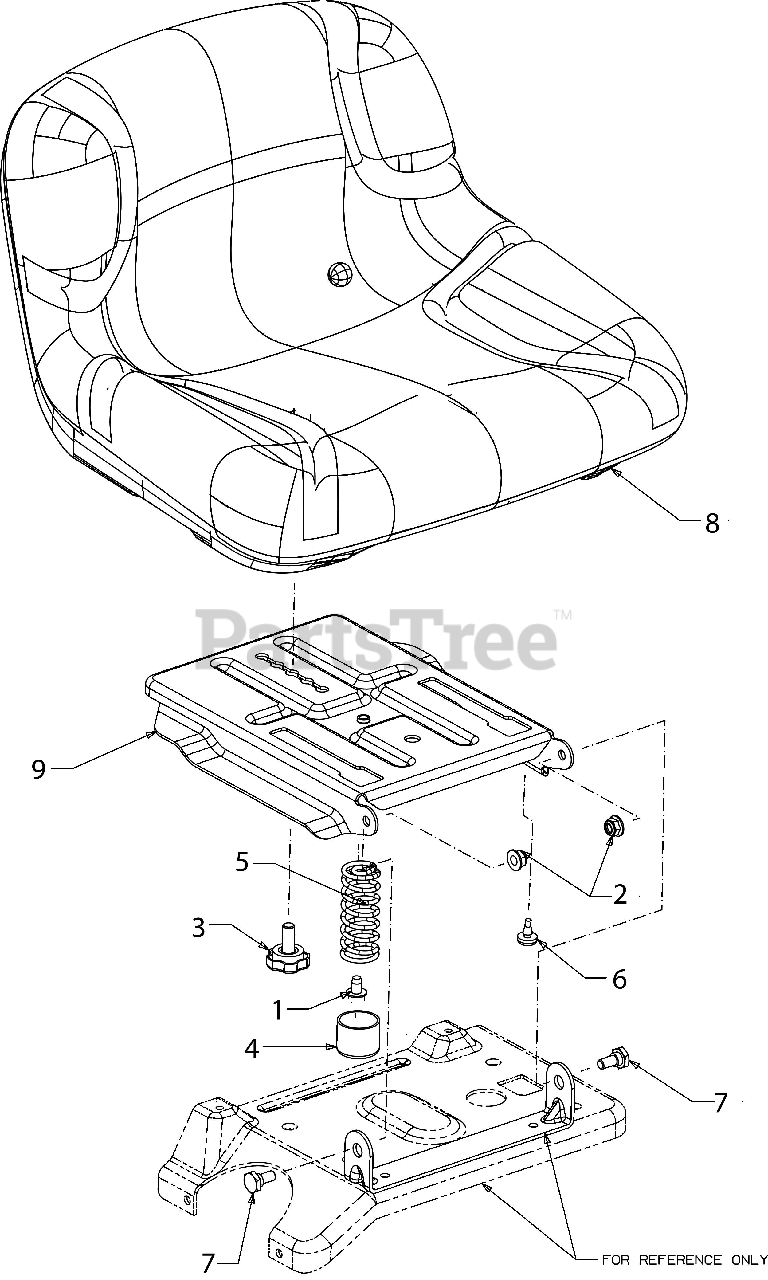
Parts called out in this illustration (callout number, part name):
1	SCREW 5/16-18 x .500
2	FLANGE LOCK NUT 5/16-18
3	SEAT ADJUSTMENT KNOB
4	SEAT SPRING CAP
5	SEAT SPRING
6	RUBBER BUMPER
7	SHOULDER SCREW .437
8	MEDIUM BACK SEAT (BLACK)
9	MANUAL SEAT ADJUSTMENT BRACKET
